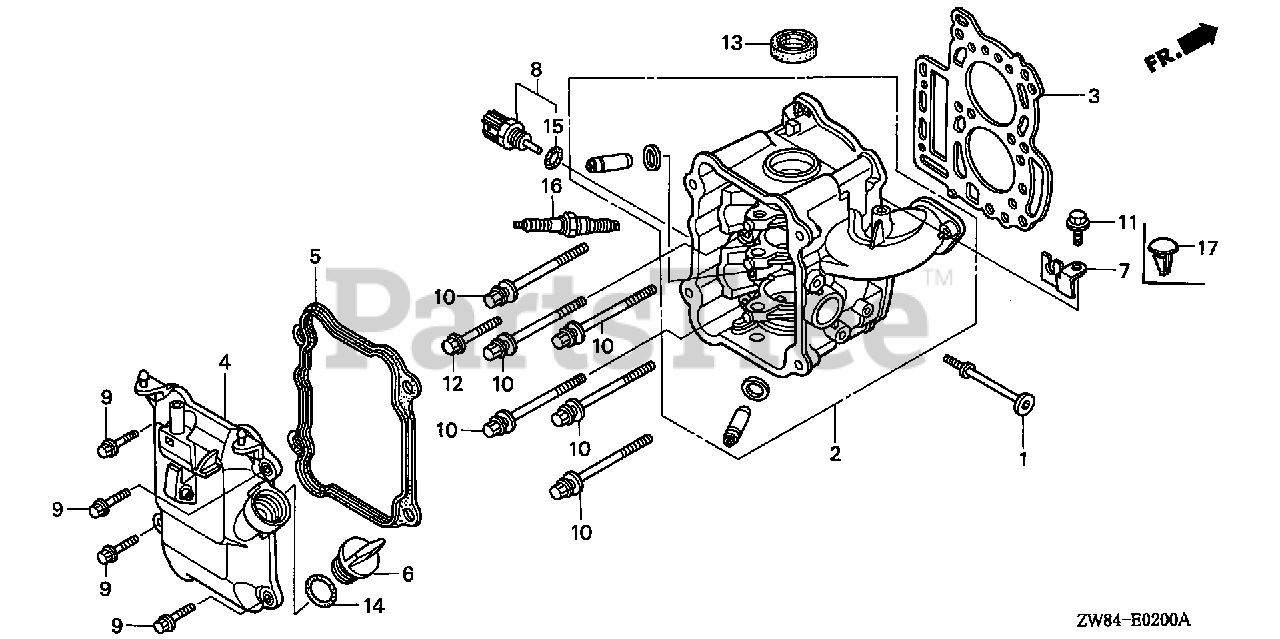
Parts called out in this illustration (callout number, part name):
1	STOPPER, ENGINE SIDE
2	CYLINDER HEAD (000) *NH8* (DARK GRAY)
3	GASKET, CYLINDER HEAD
4	COVER, HEAD
5	GASKET, HEAD COVER
8	SENSOR ASSY., WATER TEMPERATURE
9	BOLT, FLANGE (6X22)
10	BOLT, FLANGE (8X83)
12	BOLT, FLANGE (8X40)
13	OIL SEAL (20X32X6)
14	O-RING (26X2.7)
15	O-RING (9.5X1.5)
16	SPARK PLUG (CR5EH-9) (NGK)
16	SPARK PLUG (U16FER9) (DENSO)
17	PLUG, HOLE (5.4MM)
